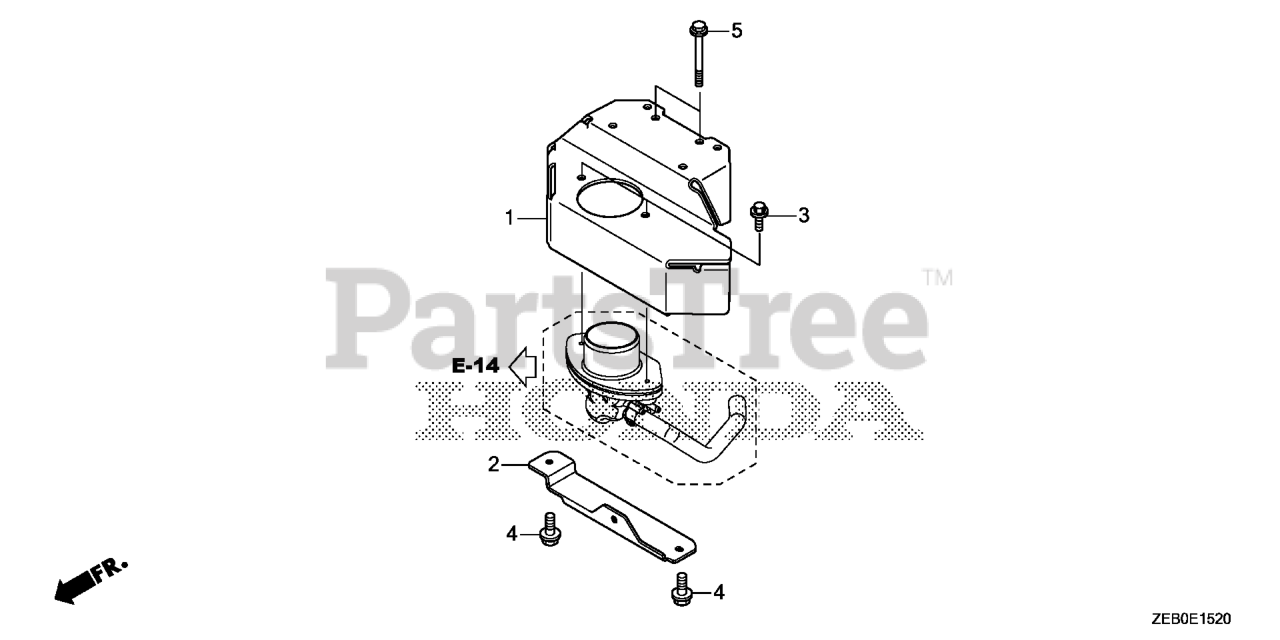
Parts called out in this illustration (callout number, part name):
1	STAY, AIR CLEANER
2	STAY B, AIR CLEANER
3	BOLT, FLANGE (6X14)
4	BOLT, FLANGE (6X16) Use from Engine SN 2056820.
5	BOLT, FLANGE (6X60)
